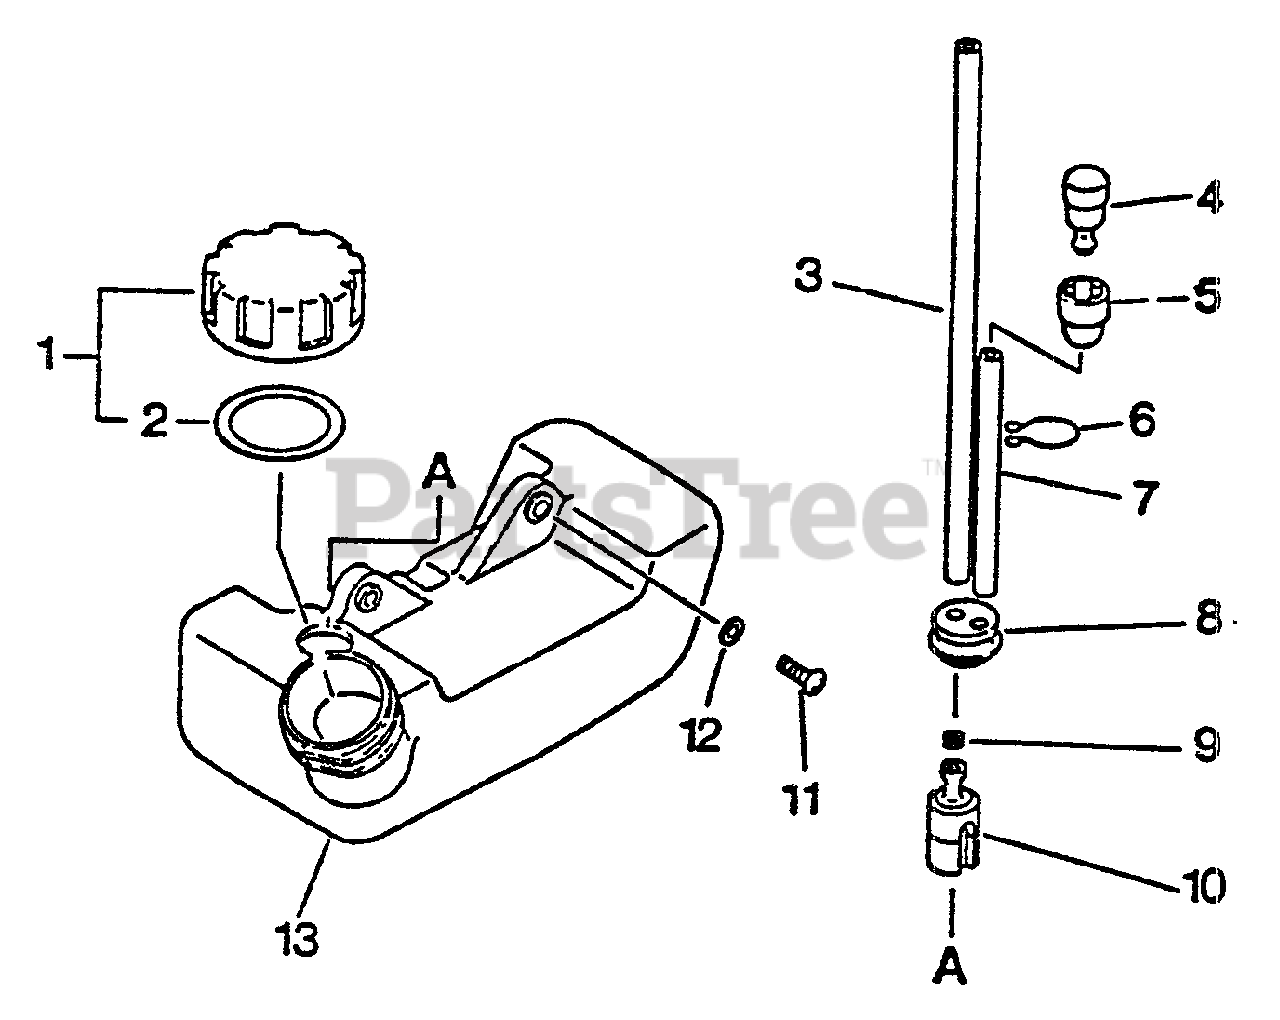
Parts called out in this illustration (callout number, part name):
1	CAP ASSY
2	GASKET, FUEL CAP
3	PIPE, FUEL 3x-5x-180
4	VENT ASSY
5	HOLDER, VENT
6	CLIP, TUBE
7	PIPE, FUEL RETURN 3×6×70
8	GROMMET, FUEL
9	CLIP 6 MM
10	FILTER, FUEL
11	SCREW 5×16
12	WASHER 5.5×12×0.8
13	TANK, FUEL
